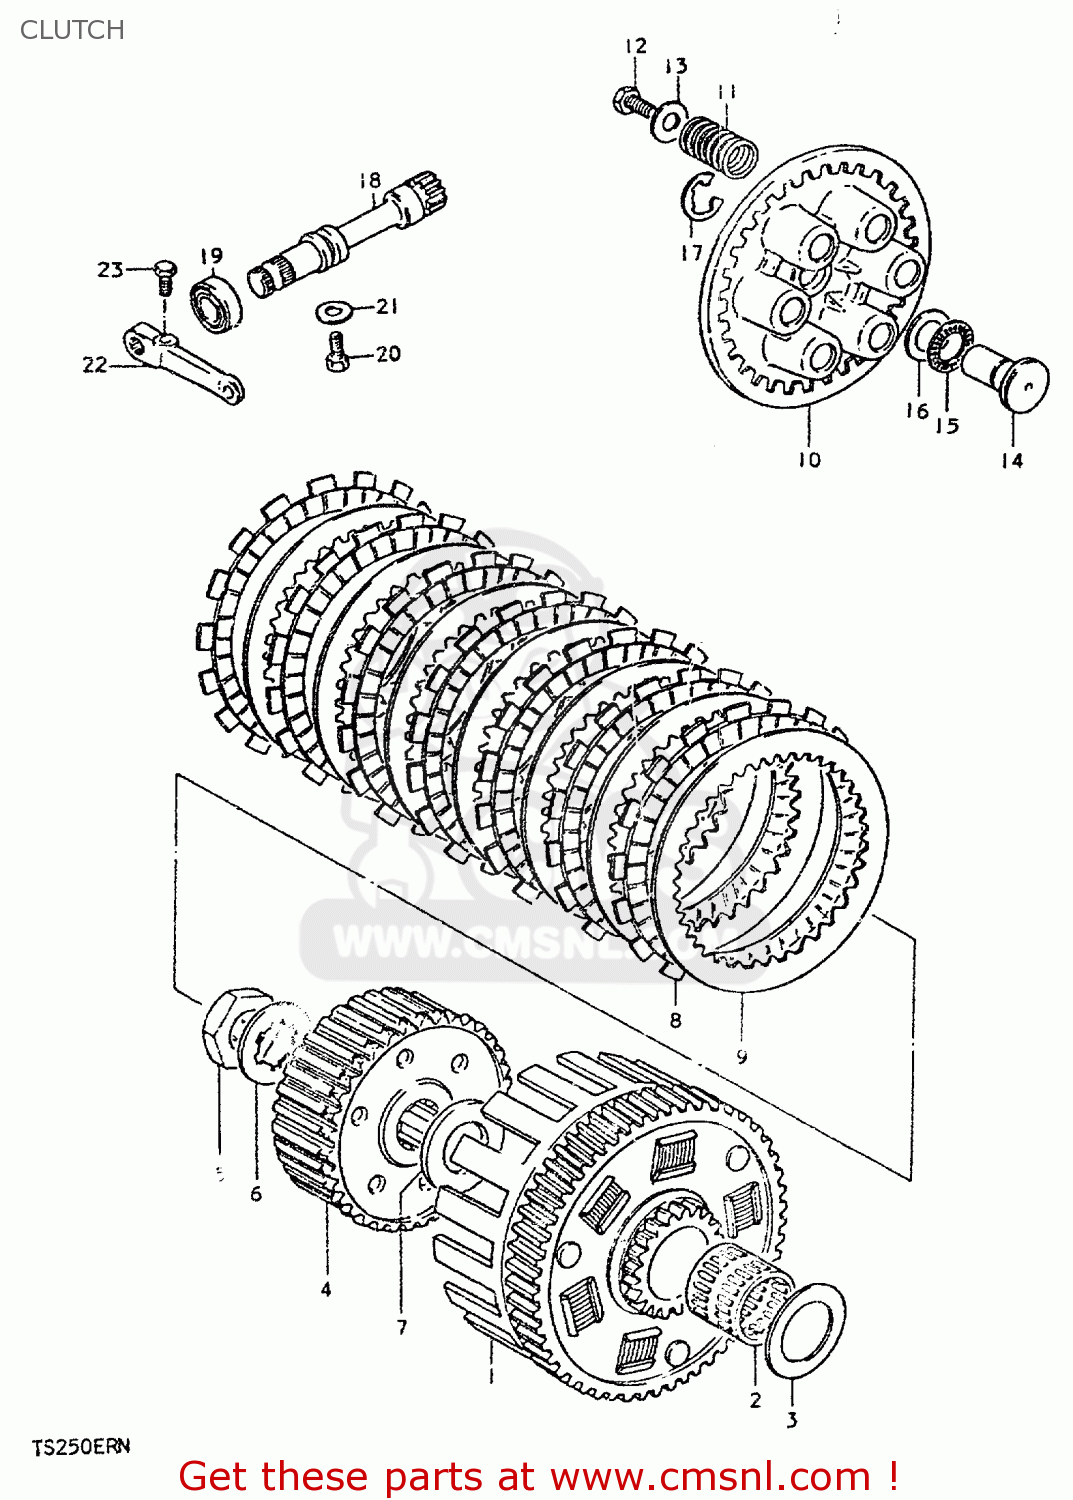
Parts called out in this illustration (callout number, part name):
1	GEAR ASSEMBLY,PRIMARY DRIVE
2	ROLLER BEARING (25X30X3
3	WASHER(25X41X3)
4	HUB,CLUTCH SLEEVE
5	NUT (20MM)
6	WASHER,LOCK
7	WASHER(20X44X3)
8	PLATE,CLUTCH DRIVE (MCA)
9	PLATE,CLUTCH DRIVEN(T:2.0) (NAS)
10	DISC,CLUTCH PRESSURE
11	SPRING
12	BOLT, UPPER
13	WASHER
14	RACK,CLUTCH RELEASE
15	BEARING(15X28X2)
16	WASHER
17	E RING 12MM
18	PINION,CLUTCH RELEASE
19	OIL SEAL
20	BOLT(6X12)
21	WASHER
22	ARM,CLUTCH RELEASE
23	BOLT
